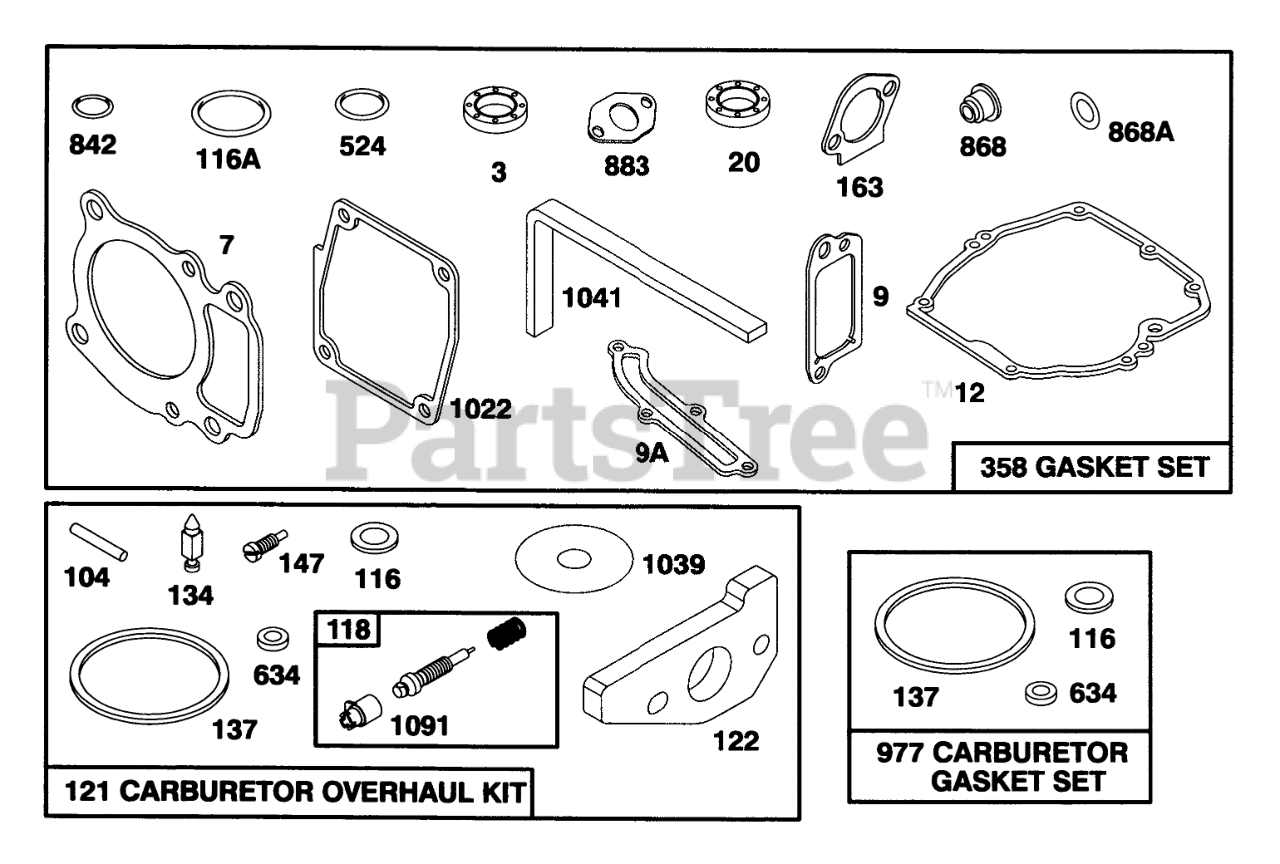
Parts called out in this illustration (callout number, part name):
3	SEAL - OIL
7	CYLINDER HEAD GASKET
9	BREATHER GASKET
9A	GASKET-BREATHER
12	ENGINE BASE GASKET
20	SEAL-OIL
104	FLOAT HINGE PIN
116	O RING SEAL
116A	O RING SEAL
118	VALVE/SPRING - NEEDLE
121	KIT-CARBURETOR OVERHAUL
122	ADAPTER ASSEMBLY
134	Valve-lnlet (Includes Seat)
137	FLOAT BOWL GASKET
147	JET - PILOT
163	AIR CLEANER GASKET
358	GASKET SET
524	O-RING
634	SEAL WASHER
842	O-RING
868	SealAssy-Valve
868A	Seal-Valve
883	EXHAUST GASKET
977	CARBURATOR GASKET SET
1022	ROCKER COVER GASKET
1039	FLOAT LIMITER
1041	SEAL - FOAM
1091	CAP - LIMITER
